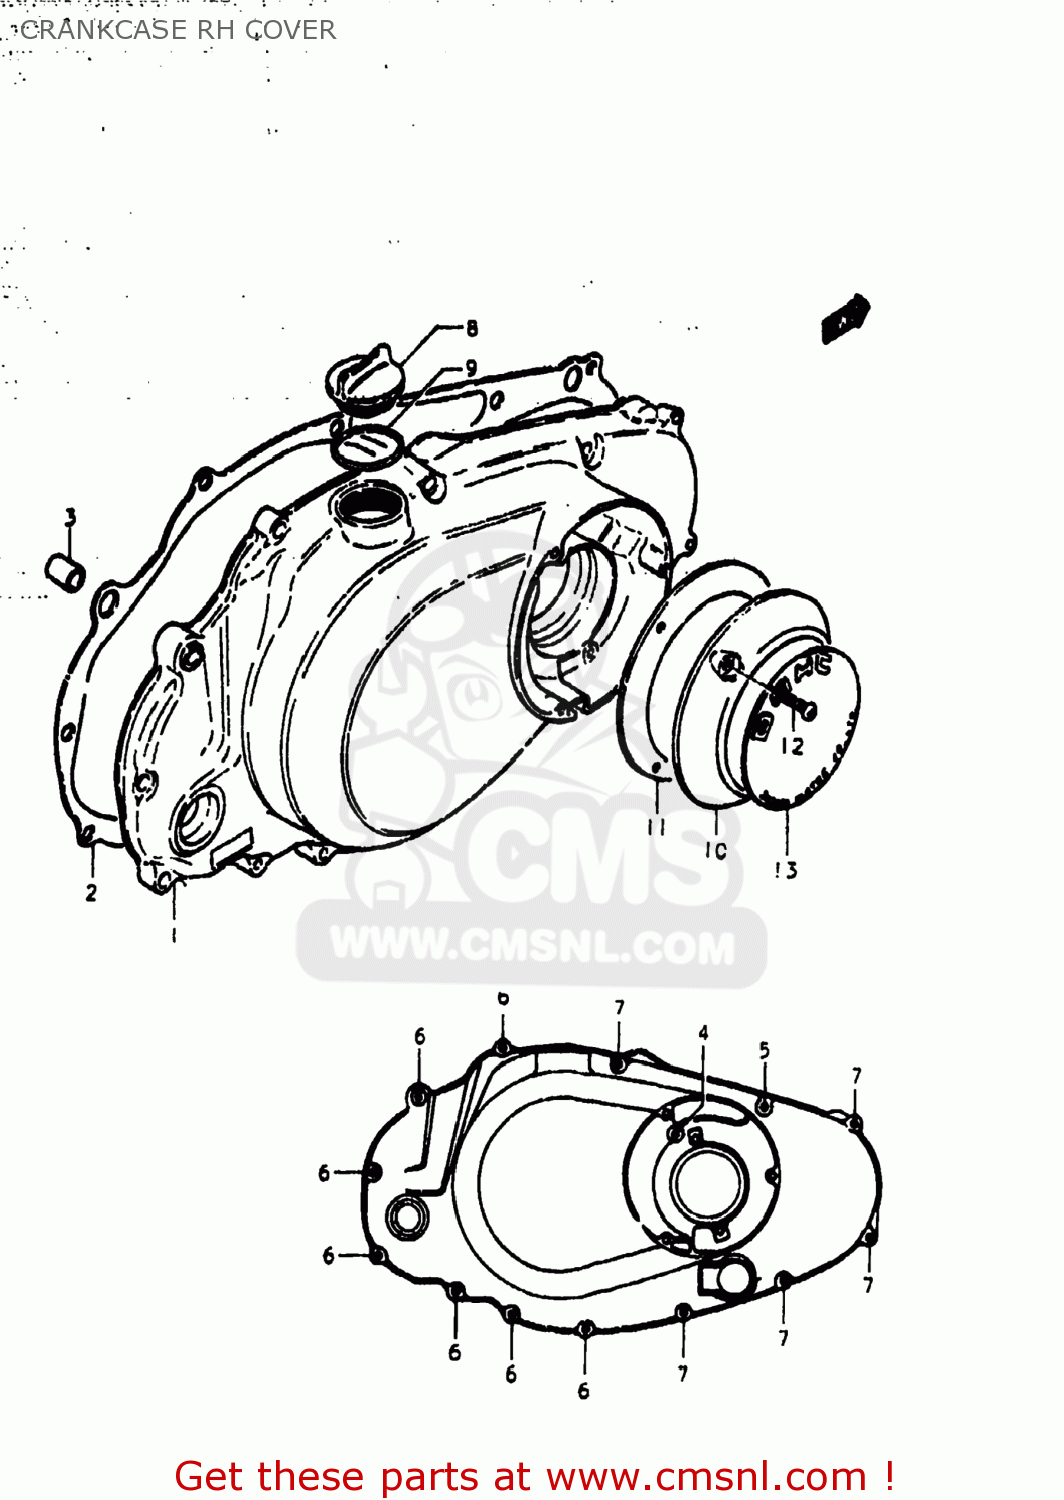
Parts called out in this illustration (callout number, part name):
1	COVER,CLUTCH
2	GASKET,CLUTCH COVER (MCA)
3	PIN
4	SCREW 6X60
5	SCREW (6X45)
6	SCREW (6X35)
7	SCREW
8	CAP
9	O RING(D:2.2,ID:32)
10	COVER,CONTACT BREAKER
11	GASKET,CONTACT BREAKER (MCA)
12	SCREW 5X20
13	EMBLEM
